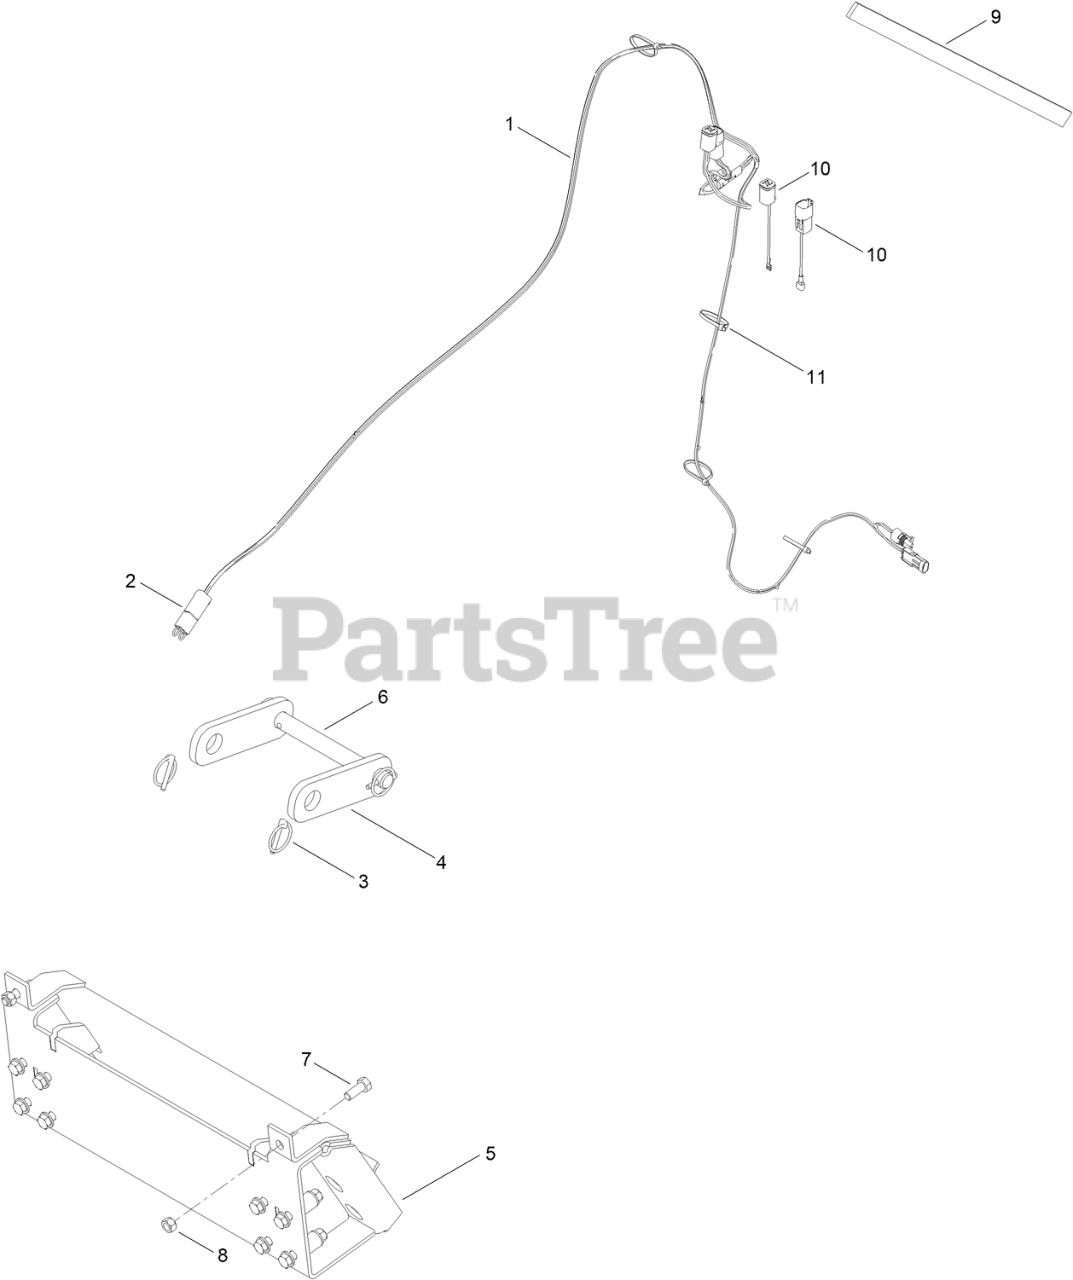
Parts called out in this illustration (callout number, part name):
1	HARNESS-WIRE, KIT
2	HARNESS-WIRE, JUMPER
3	PIN-KLIK
4	STRAP-CYLINDER LINK
5	ATTACHMENT-PLATE. ASM
6	PIN-LOCKING
7	SCREW-HH
8	NUT-HEX
9	STRAP - VELCRO
10	HARNESS-WIRE, KIT
11	TIE-CABLE
